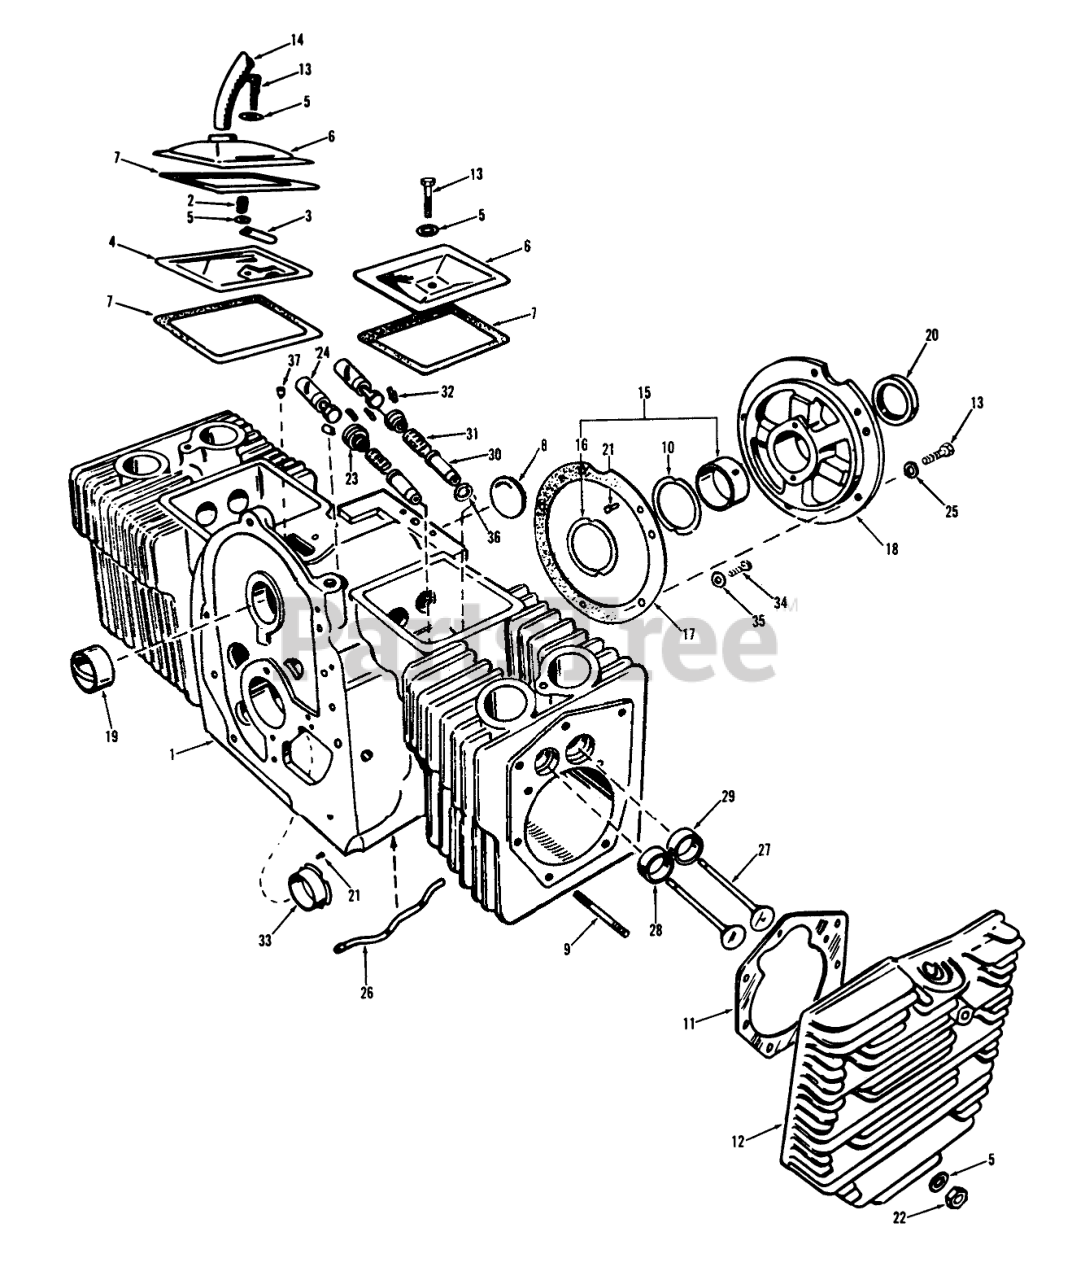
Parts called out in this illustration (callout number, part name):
1	Block Assy
2	Spring, Breather Valve
3	Breather Valve
4	Breather Baffle
5	Washer, Cyl Head Screws 5/16 in
5	Washer, Valve Compartment 1/4 in.
5	Breather Valve (1/4"-Steel)
6	Cover With Tube Opening LH
6	Cover W/O Tube Opening RH
7	Valve Cover Gasket
8	PlugCamshaft Expansion
9	Cylinder Head (5/16 x 2 5/16")
9	STUD-CYL HEAD
10	Rear Bearing Shim
11	Gasket-Cylinder Head
12	Cylinder Head RH
12	Cylinder Head LH
13	Cap Screw-Valve Cover
13	Cap Screw-Bearing Plate
14	TUBE-BREATHER
15	.020" Undersize
15	.010" Undersize
15	.002" Undersize
15	Standard
15	.030" Undersize
16	Cranksft Bearing Thrust Washer
17	Gasket, Bearing Plate
18	Bearing Plate
19	Camshaft Bearing (Precision)
20	Bearing Plate Seal
21	Pin-Main Bearing Stop
22	Cylinder Head-Hex (5/16-24)
23	Valve Spring Retainer
24	.002" Oversize
24	.001" Oversize
24	Standard
24	.005" Oversize
25	Lockwasher-Rear Bearing Plate
26	Crankcase Oil Tube
27	Intake
27	VALVE-EXHAUST
28	.005" Oversize
28	.002" Oversize
28	Standard
28	.025" Oversize
28	55095 ADD.REPLAC.PA
29	.002" Oversize
29	Standard
29	.025" Oversize
29	.010" Oversize
29	.005" Oversize
30	Valve Guide
31	Valve Spring
32	Lock-Valve and Spring Retainer
33	.002" Undersize
33	Standard
33	.030" Undersize
33	.020" Undersize
33	.010" Undersize
34	Cap Screw-Cylinder Block
35	Copper Washer 3/8-Oil Pressure
36	Gasket-Intake Valve Guide
37	Breather Hole Plug
